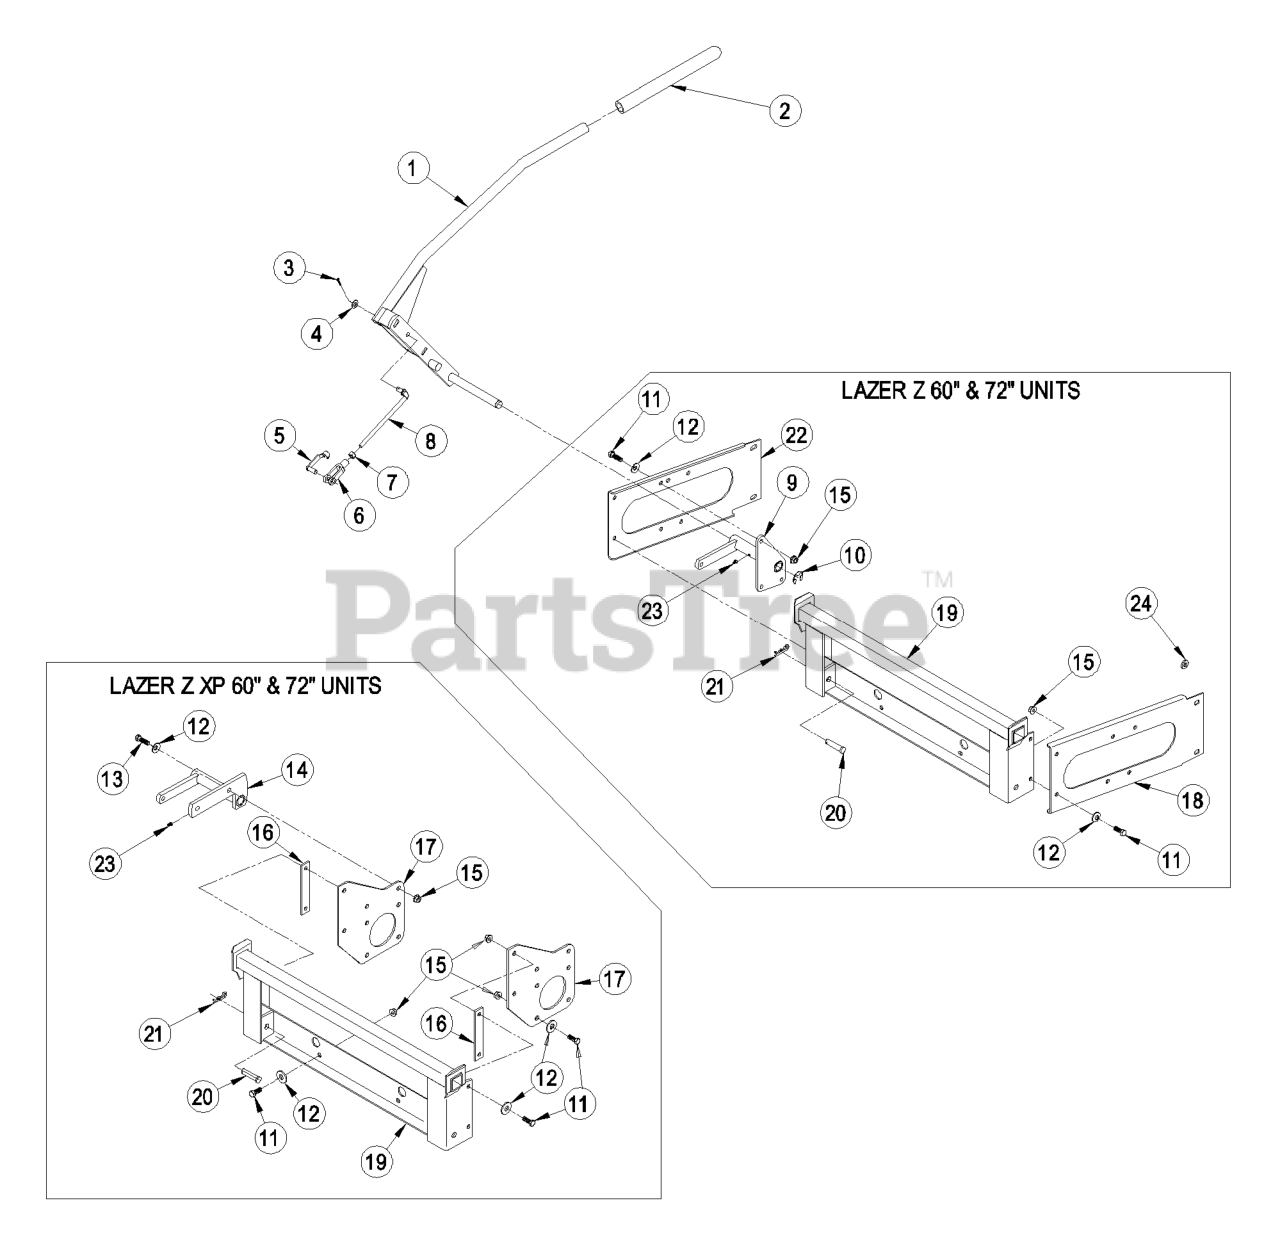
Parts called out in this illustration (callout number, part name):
1	HANDLE AND GRIP ASM
2	GRIP-HANDLE
3	PIN-COTTER
4	WASHER-FLAT
5	PIN-SPRING, CLEVIS
6	YOKE-LINKAGE, BRAKE
7	NUT-HEX
8	LINK-HANDLE
9	WLD, HANDLE MOUNT
11	SCREW-HH
12	WASHER-BELLEVILLE
13	SCREW-HH
14	WLD, HANDLE MOUNT - XP
15	NUT-HHF, WHIZ
17	PLATE-MOUNT, BAGGER
18	BRACKET-FRAME, RH
19	MOUNT-BAGGER
20	PIN-CLEVIS
21	PIN-COTTER
22	BRACKET-FRAME, LH
23	FITTING-GREASE
